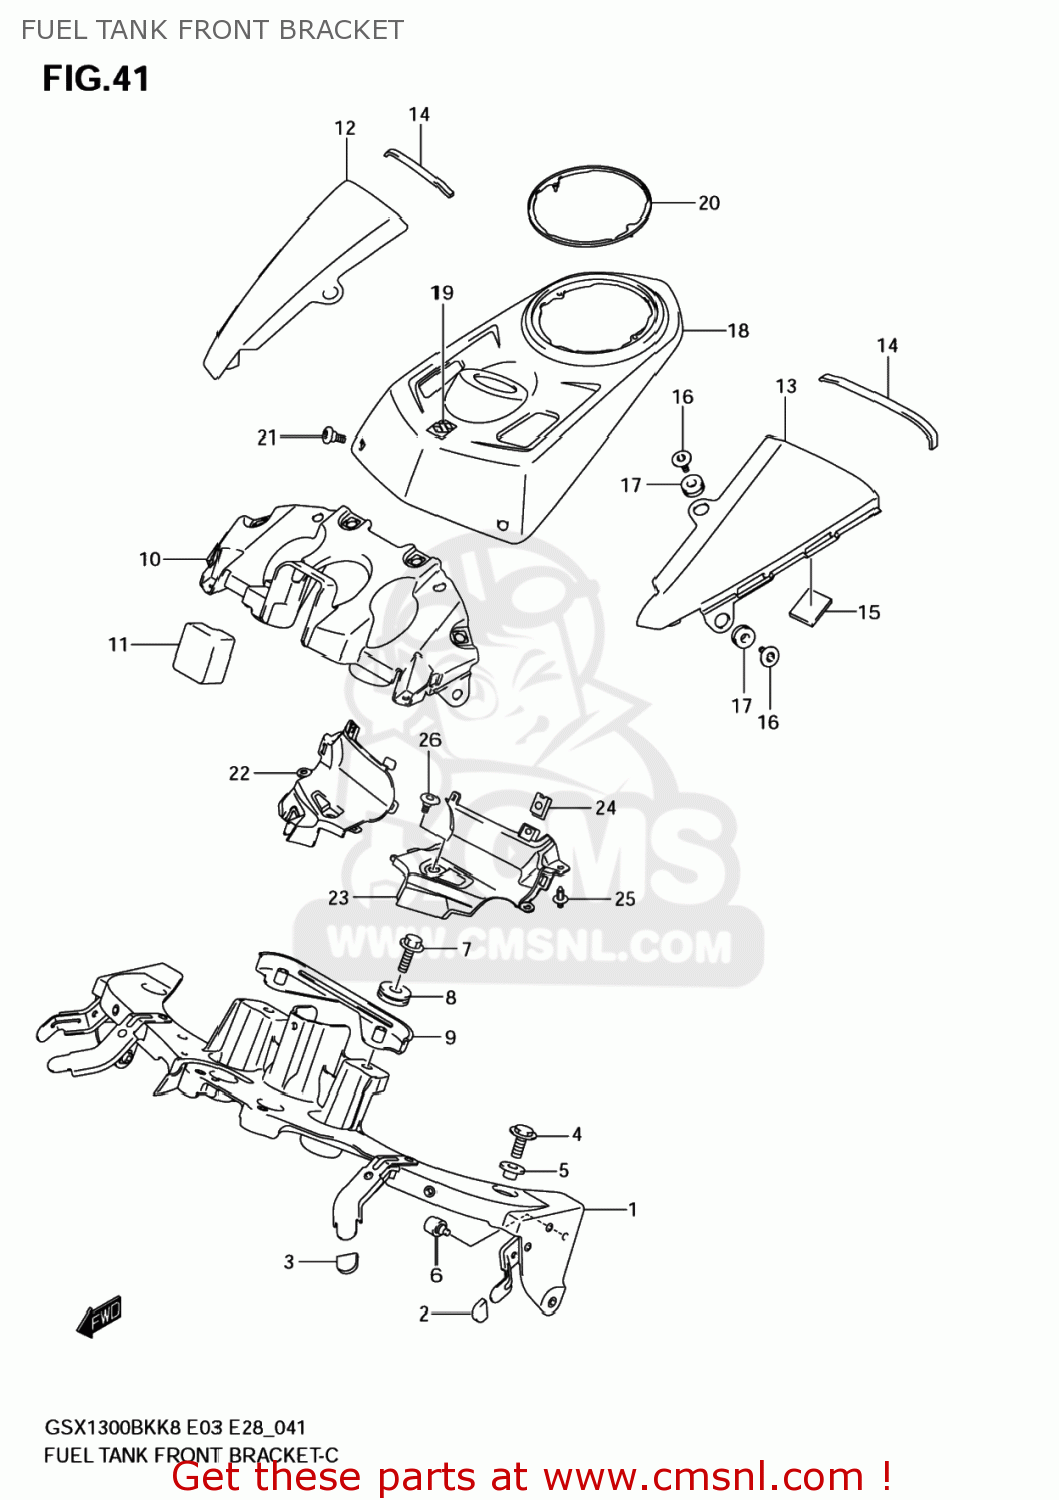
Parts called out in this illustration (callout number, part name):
1	BRACKET,FUEL TANK COVER
2	CUSHION
3	CUSHION,TANK COVER BRACKET
4	BOLT
5	WASHER
6	CUSHION,FUEL TANK COVER
7	BOLT(6X35)
8	CUSHION,FUEL TANK RR
9	WASHER,FUEL TANK FR
10	BRACKET,FUEL TANK FR
11	CUSHION,TANK FR BRACKET
12	COVER,FUEL TANK UPR,R
13	COVER,FUEL TANK UPR,L
14	CUSHION,UPR COVER
15	FASTENER
16	SCREW(5X16.4)
17	CUSHION
18	COVER,FUEL TANK UPR
19	EMBLEM,S
20	RUBBER,FUEL TANK UPR COVER
21	SCREW(5X13)
22	COVER,FUEL TANK CTR,R
23	COVER,FUEL TANK CTR,L
24	NUT
25	CLIP
26	BOLT(5X13)
